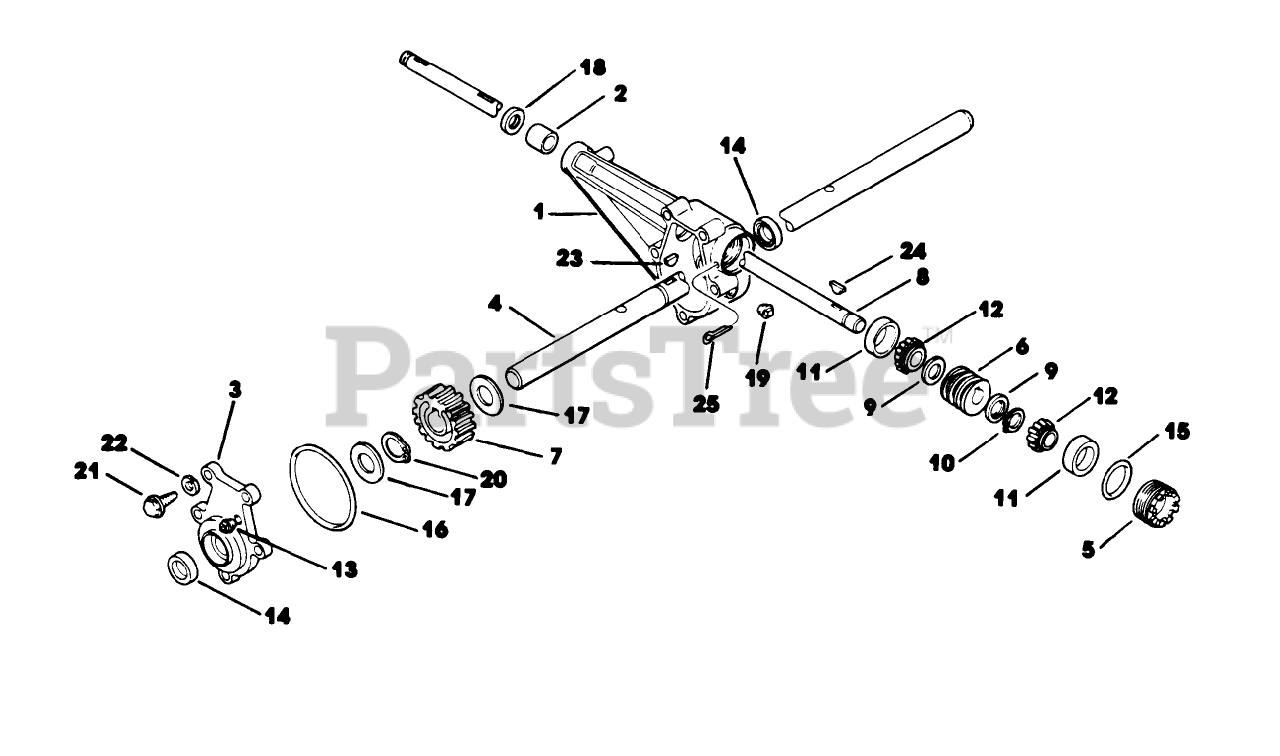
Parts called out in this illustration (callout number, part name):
1	GEAR CASE W/BUSH
5	ADJ. PLUG S
8	SHAFT-AUGER INPUT
10	RING-RETAINING
20	RING - RETAINING
